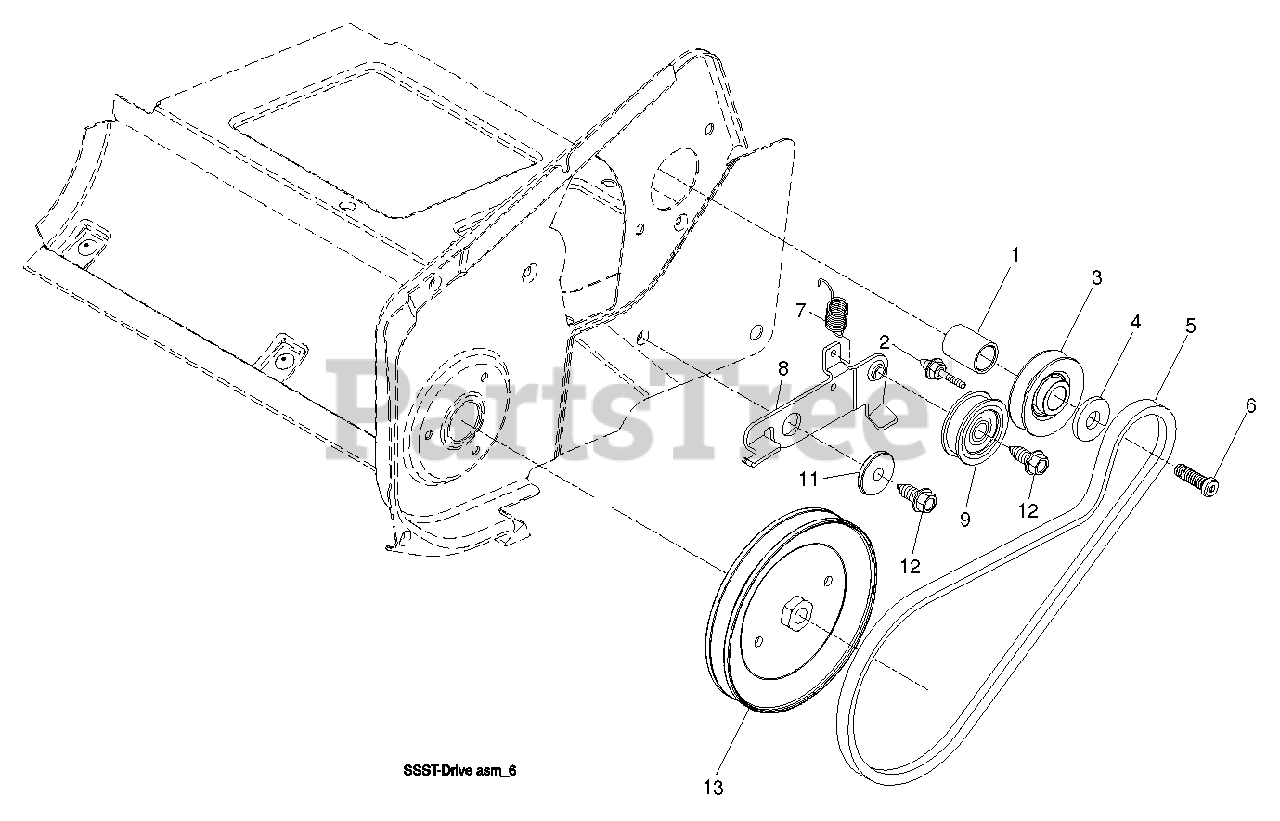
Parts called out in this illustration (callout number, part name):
1	SPACER.ENGINE.CRANK
2	KEEPER.ENGINE.BELT
3	PULLEY.ENG.TRACTION
4	WASHER,HARDEN
5	BELT.4L.1/2X35
6	BOLT, SCKT HD 3/8-24 X 1 .25
7	SPRING.EIDLER.PULLEY.RETURN
8	ARM.IDLER.PNT.MS431
9	IDLER PULLEY
11	SPACER.RETAINER
12	SCREW.3/8-16
13	PULLEY.DRIVEN
